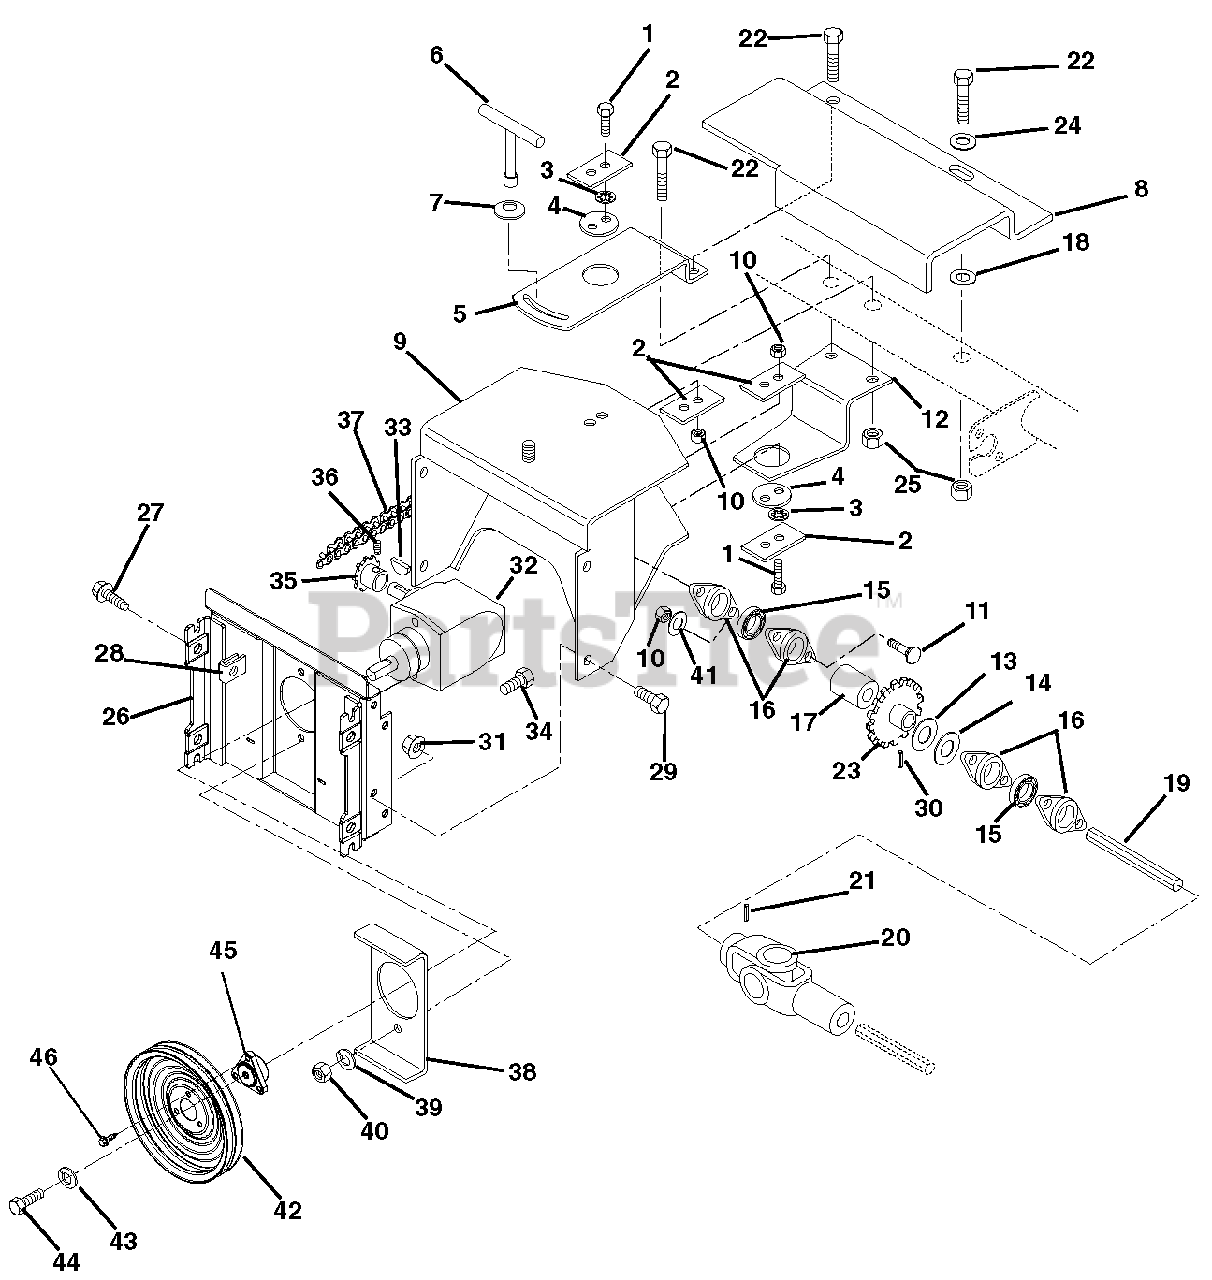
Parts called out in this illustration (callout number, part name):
1	Bolt, Hex .31-18 x 1.25 Grade 5
2	Retainer
3	Washer, Locking External .326 x .599 x .031
4	Pivot, Center
5	Plate, Top Mount
6	T-Lock Handle
7	Washer, Bellville .63 x 1.625 x .14
8	Guard, Shaft
9	Frame, Adapter
10	Nut, Locking Center .31-18
11	Bolt, Round Head Square Neck .31-18 x .75 Grade 5
12	Plate, Bottom Mount
13	Washer, Flat Steel 1.031 x 1.625 x .188
14	Washer, Flat Steel 1.03 x 1.31 x .105
15	Bearing, Ball
16	Flange, Bearing
18	Washer, Flat Steel .390 x .88 x .18
20	Universal Joint
21	Pin, Roll .188 x 1.50
22	Bolt, Hex .38-16 x 3.25 Grade 5
23	Sprocket
24	Washer, Flat Steel .406 x .812 x .065
25	Nut, Locking Center .38-16
26	Plate, Mounting Broom
27	Bolt, Hex Flanged Whizloc Head .38-16 x .75
28	Nut, Retainer .38-16
29	Bolt, Hex .38-16 x .75 Grade 5
30	Pin, Roll .188 x 1.75
31	Nut, Locking Center .38-16
32	Gear Box Assembly
33	Key, Woodruff .188 x .75 x .313 SAE 9
34	Bolt, Hex .38-16 x 1.25 Grade 5
35	Sprocket
36	Screw, Set .25-20 x .38 Socket Head Cup Point
38	Plate, Stiffener
39	Washer, Lock .38 x .094
40	Nut, Hex .38-16
41	Washer, Flat Steel .38 x .875 x .083
42	Pulley, Spin Form Dual Groove
43	Washer, Lock .312 x .097
44	Bolt, Hex .312-24 x .75 Grade 5
45	Pulley Hub, D-Bore .87 Pro
46	Screw, Tapping .31-18 x .50 Hex Washer Head
